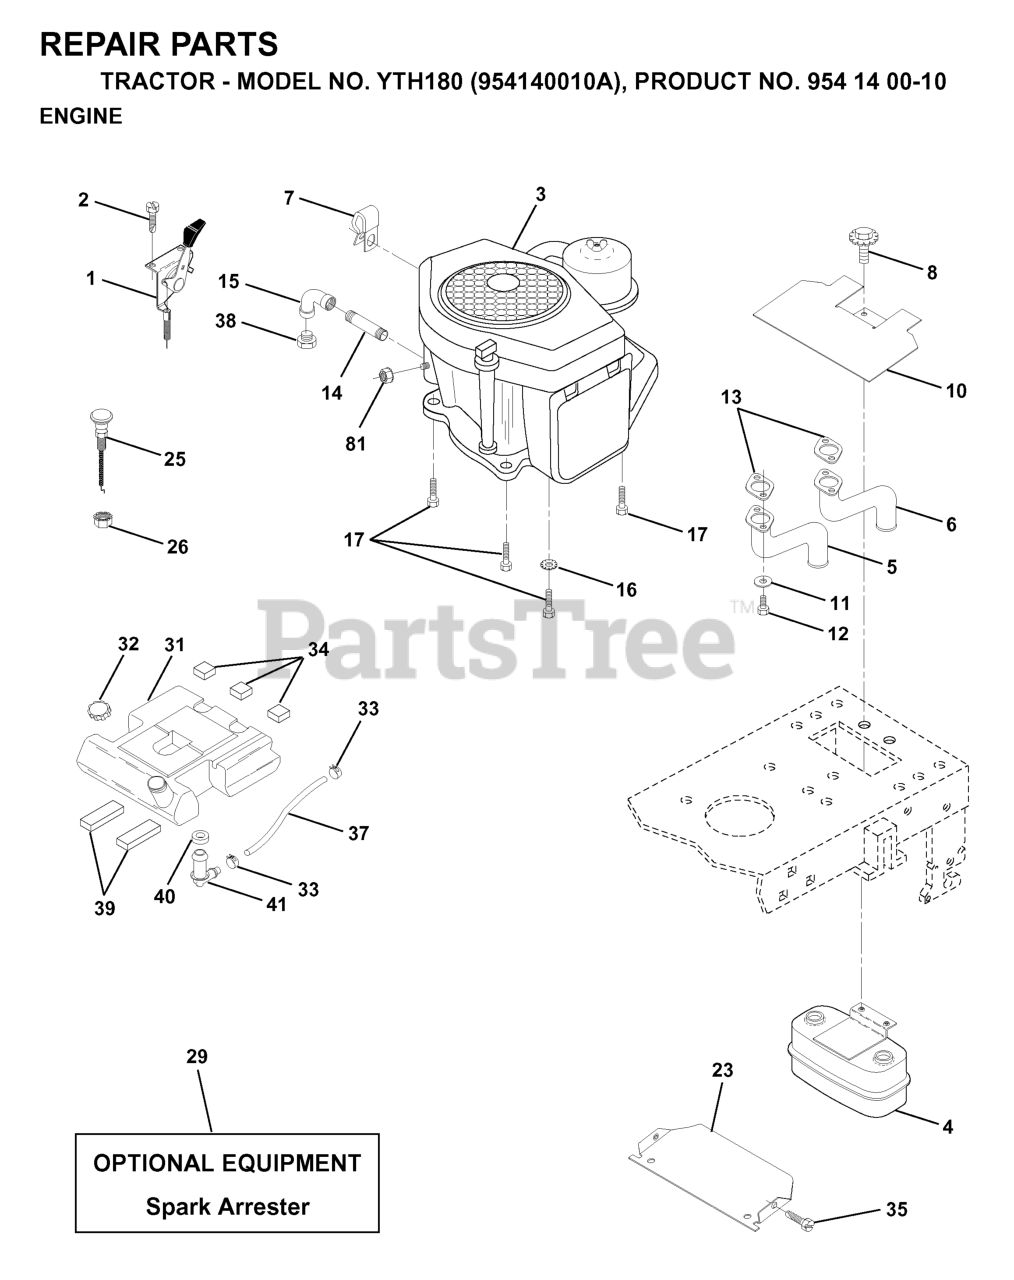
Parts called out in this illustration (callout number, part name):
1	CONTROL THROTTLE
2	SCREW LT
4	MUFFLER.TWIN.CYL.LOW.TONE
5	RP.PIPE-EXHAUST LH
6	RP.PIPE-EXHAUST RH
7	CLIP T
8	BOLT HEX WASHER HD 5/16-18
10	RP SHIELD HEAT MUFFLER
14	Nipple, Pipe 3/8 NPT x 4-1/2
15	ELBOW
16	LOCKWASHER
17	SCREW LT
23	SHIELD HEAT
25	CONTROL, CHOKE
26	Nut Keps 3/8 - 24 UNF
29	KIT.SPARK ARRESTOR 794945 B&S
31	FUEL TANK
32	FUEL CAP
33	HOSE CLAMP
34	PAD-SPACER LT
35	SCREW.THDROL.5/16-18X3/4.TTY
37	HOSE T
39	PAD IDLER TI
40	BUSHING OUTLET T
41	STEM FUEL TANK
81	NUT FLANGE 1/4-20 STARTER NUT
